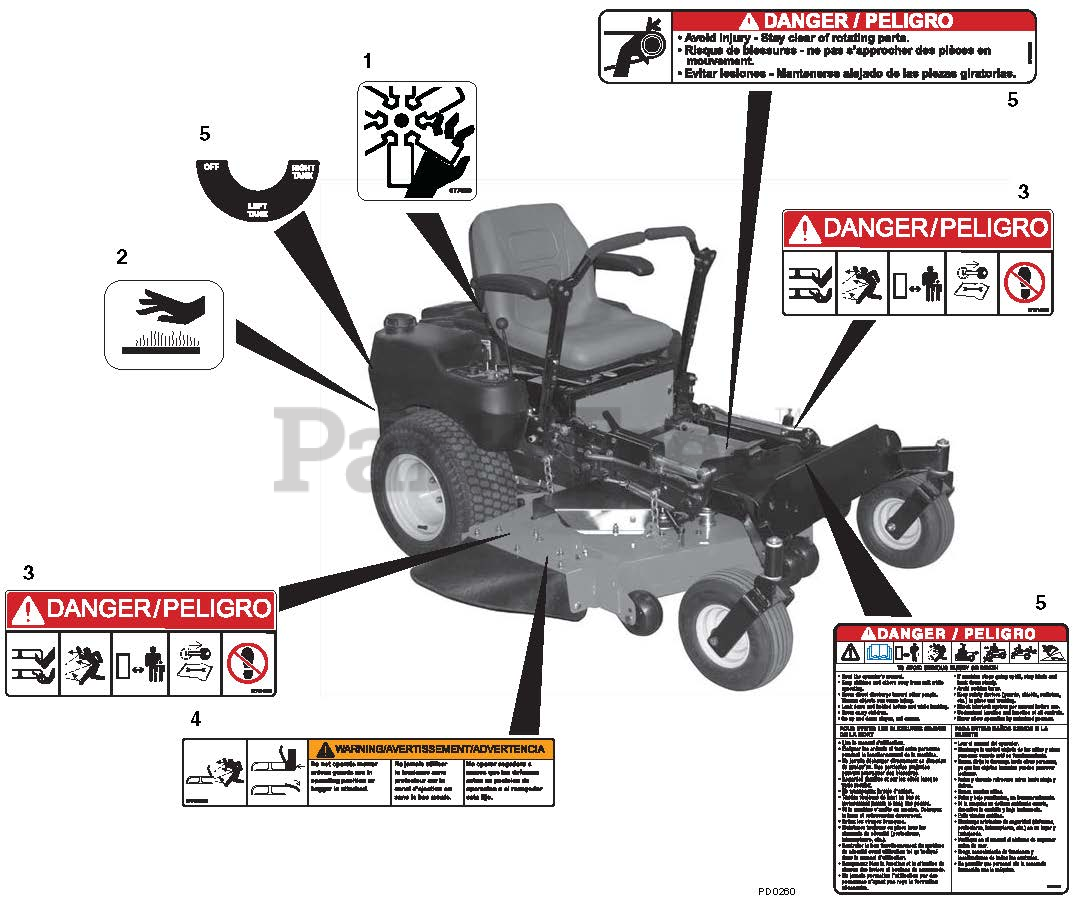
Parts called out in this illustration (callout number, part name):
1	DECAL, DANGER FAN
2	DECAL, HOT SURFACE
3	DECAL, MOWER PAN DANGER
4	DECAL, WARNING
5	SET-DECAL, COMMON DANGER/FUEL
